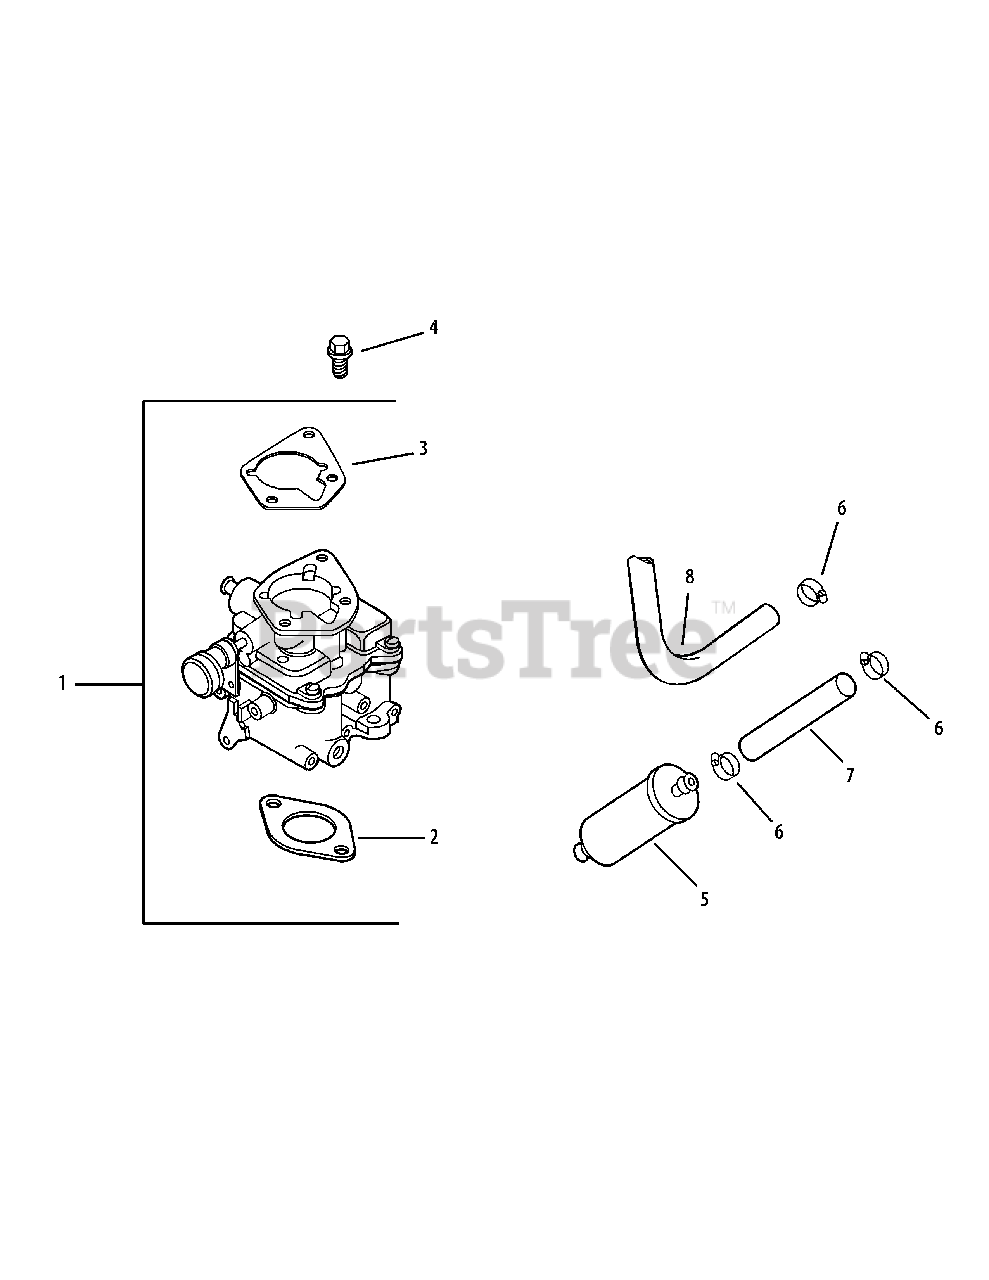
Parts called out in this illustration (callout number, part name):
1	Carburetor W/Gaskets KSF
2	Gasket, Air Cleaner Base
3	Gasket, Carburetor
4	Screw, hex Flg M6x1.0x25
5	Filter, Fuel
6	Clamp, Hose 1/2"
7	Line, Fuel 10"
8	Line, Flex 11" Pump-Pulse (Air Only)
